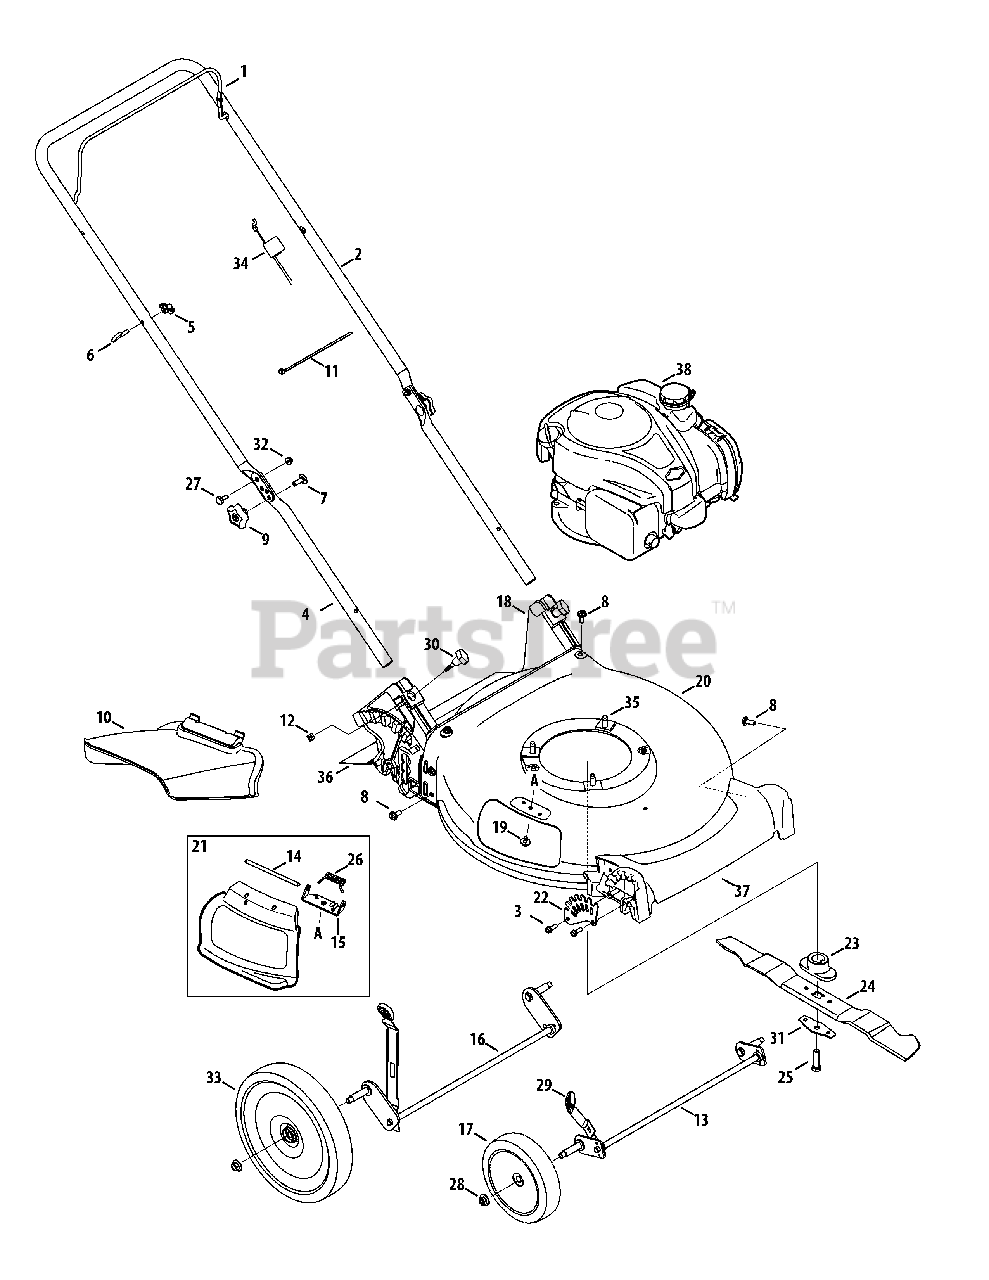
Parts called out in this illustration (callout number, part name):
1	Blade Control
2	Upper Handle
3	Screw, 1/4-15 x .750
4	Lower Handle
5	Wing Nut
6	Rope Guide
7	Carriage Screw ,5/16-18
8	Screw, 5/16-14 x .750
9	Hand Knob
10	Side Chute
11	Cable Tie
12	Nut, Sq., 1/4-20
13	Front Axle Assembly
14	Hinge Pin
15	Chute Deflector Bracket
16	Rear Axle Assembly
17	Wheel, 7 x 1.8
18	Rear Baffle
19	Screw, 1/4-20 x .500
20	Deck - 21"
21	Hinged Mulch Plug Assembly
22	Front Height Adjuster Plate
23	Blade Adapter
24	Mulching Blade
25	Screw , 3/8-24 x 1.50
26	Torsion Spring
27	Sldr. Screw, .375 x .126 x 1/4-20
28	Flange Lock Nut, 3/8-16
29	Adjustment Lever Knob
30	Wing Nut
31	Blade Bell Support
32	Nut, Flange Lock, 1/4-20
33	Wheel, 11 x 1.8
34	Control Cable
35	TT Sems Screw, 3/8-16 x 1.0
36	Trail shield
37	Front Cover
38	Engine - 09702-0007-F1
